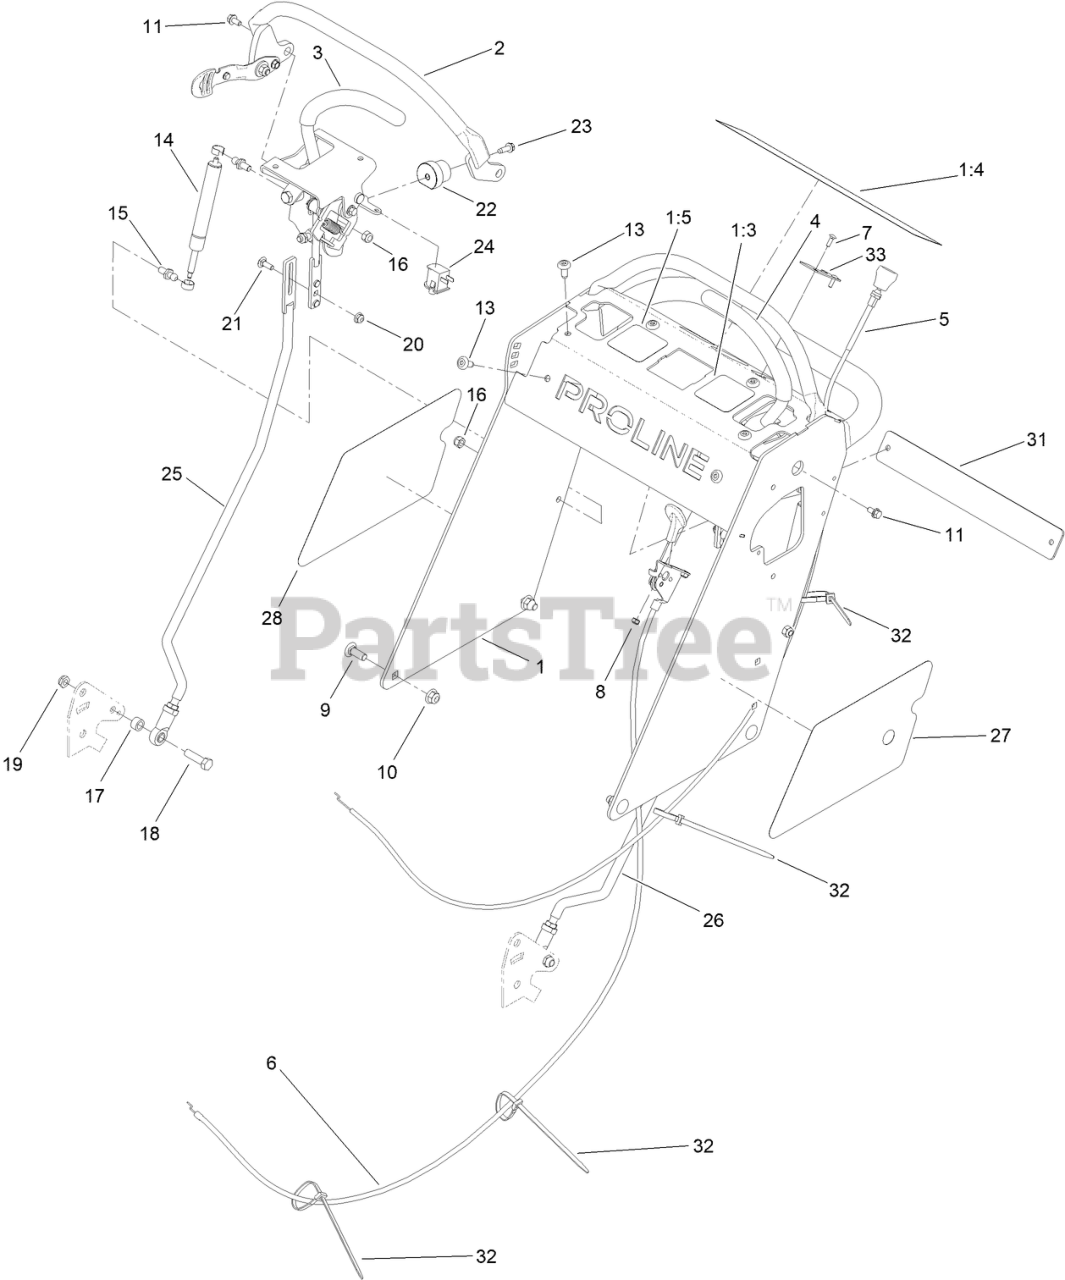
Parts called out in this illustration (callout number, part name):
1	TOWER ASM
1:3	DECAL-OPC CONTROL, LEFT
1:4	DECAL-WARNING, CONTROL
1:5	DECAL-OPC CONTROL, RIGHT
2	REFERENCE BAR ASSEMBLY
3	CONTROL HANDLE ASM, RH
4	CONTROL HANDLE ASM, LH
5	CABLE, CHOKE
6	CONTROL-THROTTLE
7	SCREW-CARR
8	NUT-LOCK, NI
9	SCREW-CARR
10	NUT-HF, NI
11	SCREW-HWH
14	DAMPER
15	STUD-BALL
16	NUT-LOCK, NI
17	SPACER
18	SCREW-HH
20	NUT-HF
21	BOLT-CARR
23	SCREW-HWHTF
24	SWITCH-BAIL
25	CONTROL ROD ASM, RH
26	CONTROL ROD ASM, LH
27	DECAL-PROLINE, LH
28	DECAL-PROLINE, RH
31	PLATE-COVER
32	TIE-CABLE
33	PLATE-SPEED LIMITER
